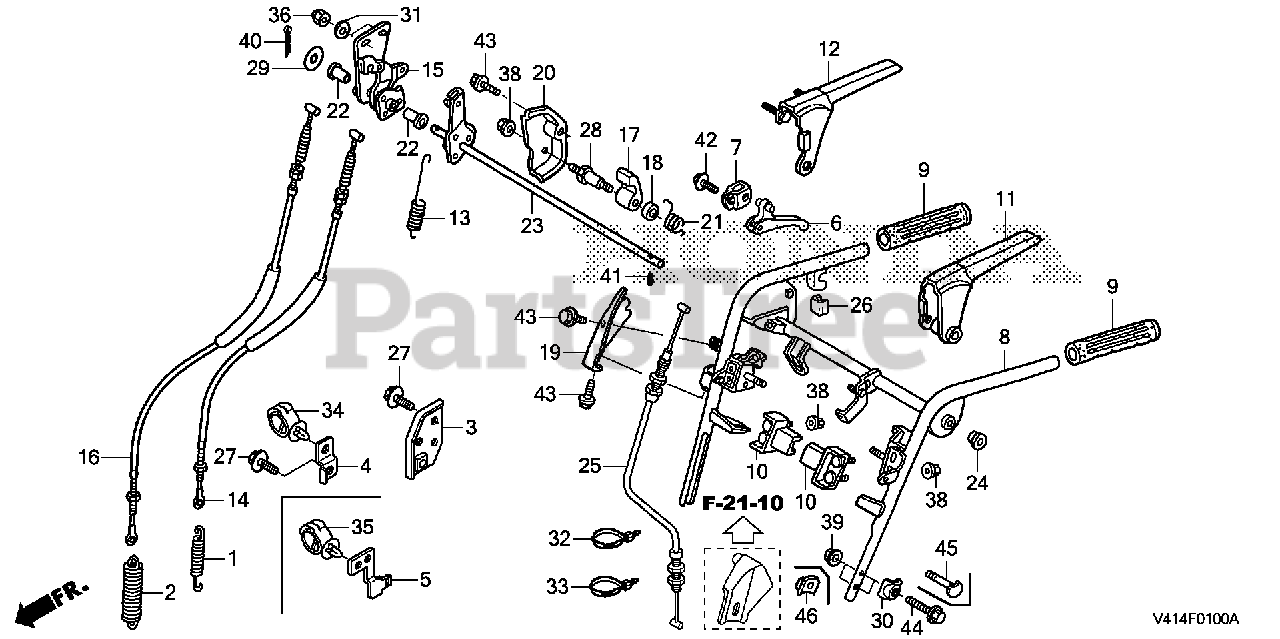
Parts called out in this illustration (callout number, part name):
1	SPRING, TENSIONER ROLLER
2	SPRING, TENSIONER ROLLER (AUGER)
4	BASE, CLIP
8	PIPE, HANDLE (UPPER) (COO)
9	GRIP, HANDLE (COO)
10	STOPPER, CHANGE LEVER
11	LEVER, CLUTCH
12	LEVER, AUGER CLUTCH
13	SPRING, CLUTCH LEVER
14	CABLE, CLUTCH
15	BOSS, CAM LOCK
16	CABLE, AUGER CLUTCH
17	RATCHET, LEVER
18	COLLAR, RATCHET
19	COVER B, RATCHET
20	COVER, RATCHET
21	SPRING, RATCHET
22	BUSH (13X22.5) (GRAY)
23	SHAFT, CLUTCH LEVER
24	BUSH (14MM)
27	BOLT, FLANGE (6X12) (CT200)
28	BOLT, PIVOT (6MM)
29	WASHER, THRUST (10MM)
30	WASHER, FRAME JOINT
31	WASHER (6MM)
34	CLIP, WIRE HARNESS (25MM)
36	NUT, CAP (6MM)
38	NUT, FLANGE (6MM)
39	NUT, FLANGE (8MM)
40	PIN, COTTER (3.0X18)
41	PIN, SPRING (4X16)
43	BOLT, FLANGE (6X10)
44	BOLT, FLANGE (8X45)
46	WASHER, FRAME JOINT
